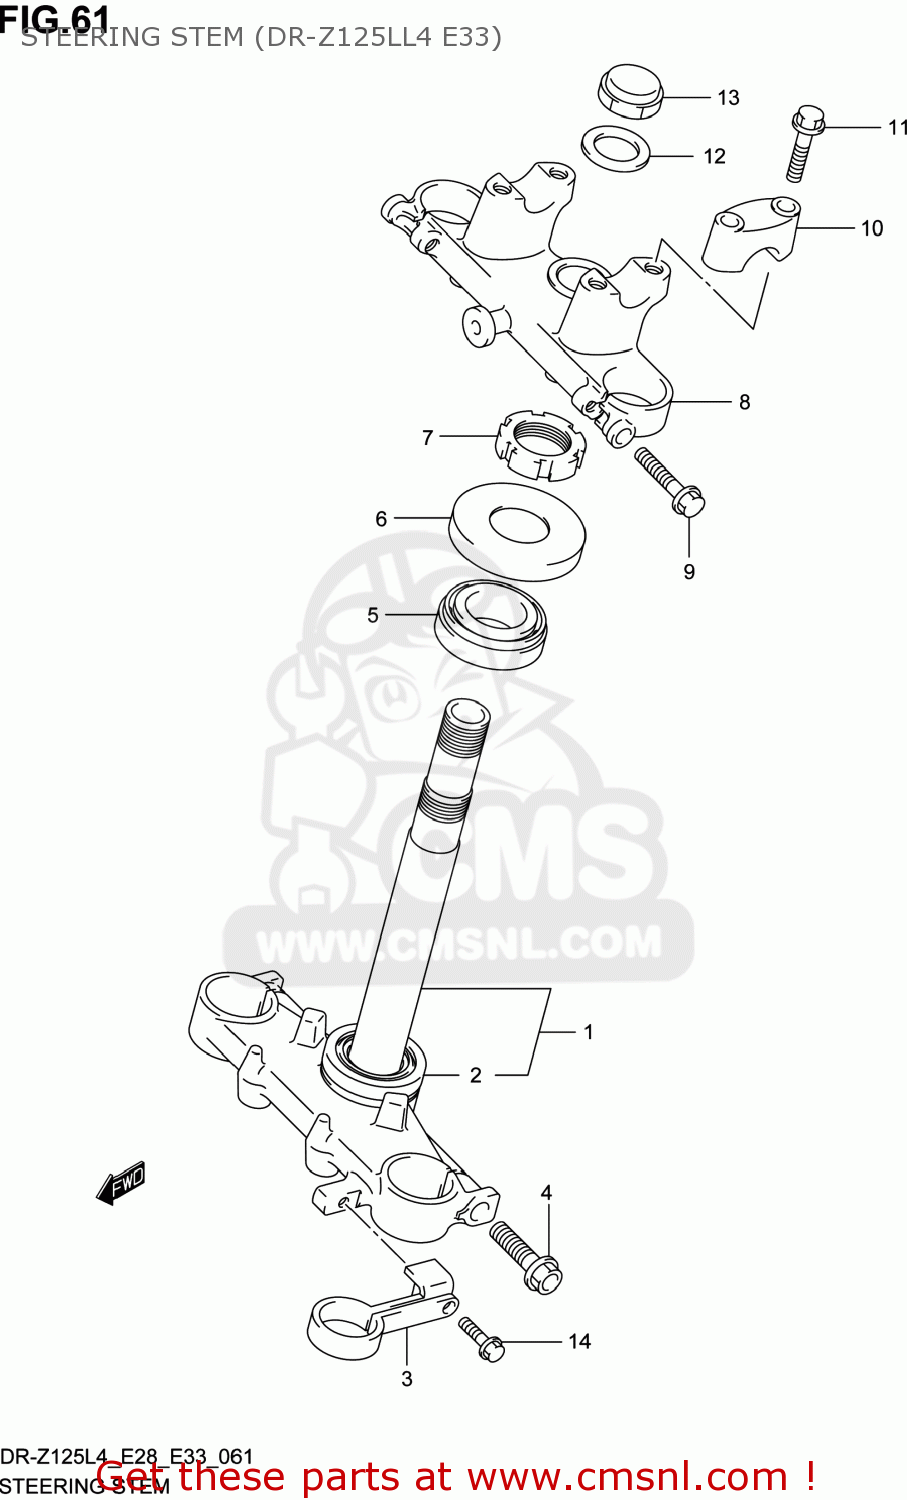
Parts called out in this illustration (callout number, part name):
1	STEM,STEERING
2	BEARING(26X47X15)
3	GUIDE,FR BRAKE HOSE
4	BOLT
5	BEARING(25X47X15)
6	SEAL,STEERING UPR DUST
7	NUT,STEERING
8	BRACKET,UPR
9	BOLT
10	HOLDER,HANDLE
11	BOLT
12	WASHER
13	NUT
14	BOLT
